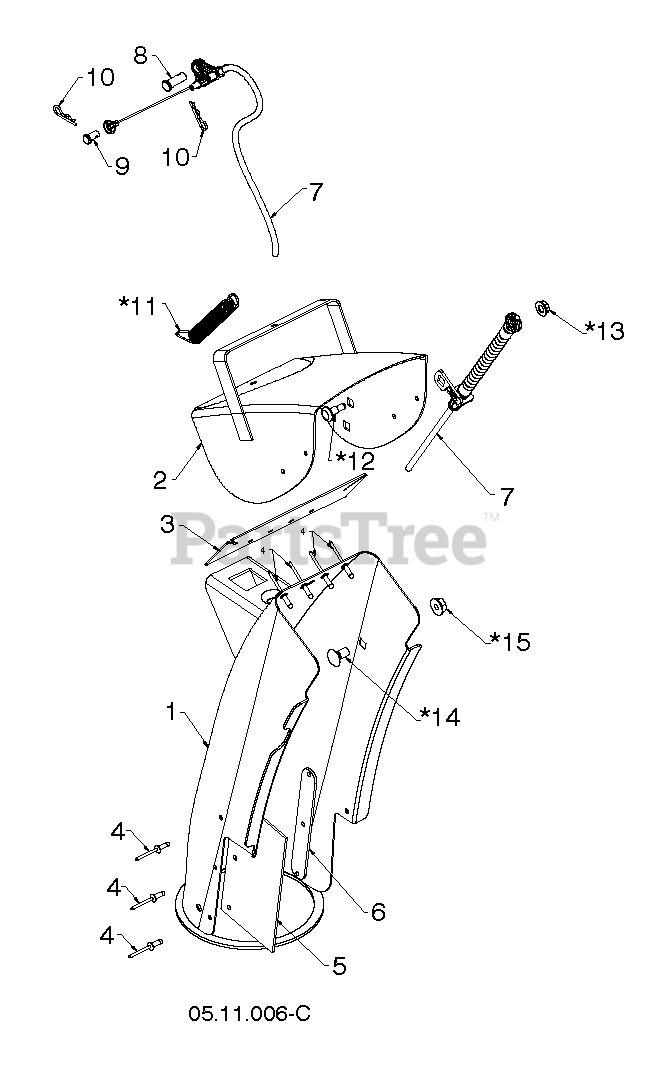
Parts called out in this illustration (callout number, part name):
1	DEFLECTOR.WELDMENT.RED
7	Deflector Chute Control Cable
8	Clevis Pin, 5/16 X .875
9	Clevis Pin, .25 X .31
10	Hair Pin, .059 X 1.125
12	Shoulder Bolt, 1/4
13	Flange Hex Lock Nut, 1/4-20 Large
14	Carriage Bolt, 5/16-18 X 5/8 Black
15	LOCKNUT-FLANGE 5/16-18
